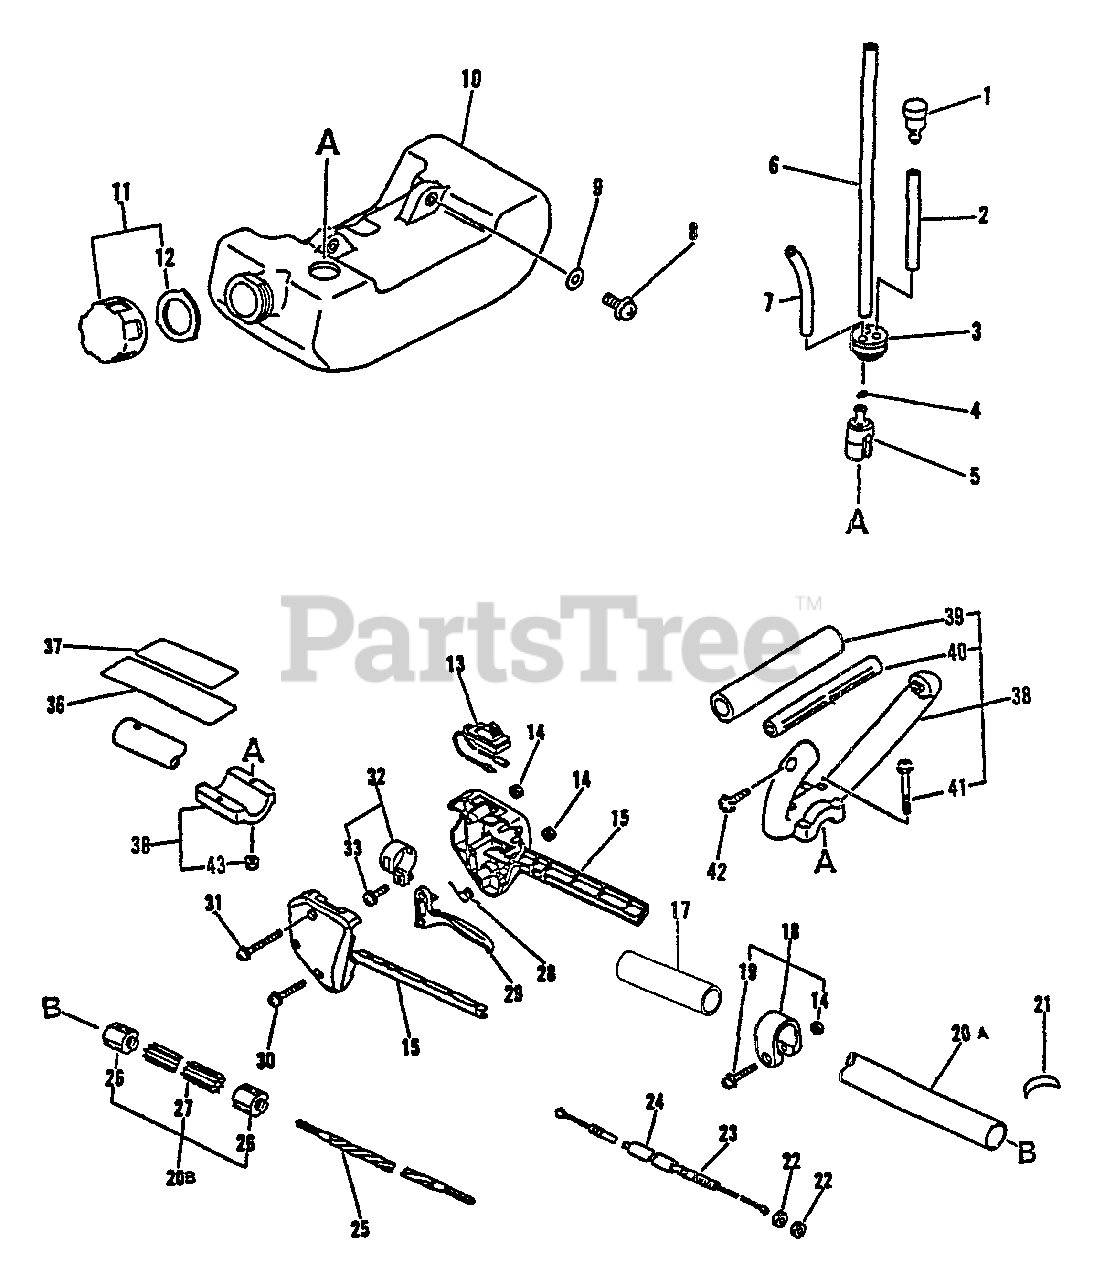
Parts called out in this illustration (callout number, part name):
1	VENT ASSY
2	PIPE, FUEL 3x-5x-70 BLACK
3	GROMMET, FUEL
4	CLIP 6 MM
5	FILTER, FUEL
6	PIPE, FUEL 3x-5x-180
7	PIPE, FUEL RETURN 3×6×90 MM CLEAR
8	SCREW 5×16
9	WASHER 5.5×12×0.8
10	TANK, FUEL
11	CAP ASSY
12	GASKET, FUEL CAP
13	IGNITION SWITCH ASSY
14	NUT M5
15	HANDLE KIT, CONTROL
17	GRIP, HANDLE
18	CLAMP KIT
19	SCREW 5×28
20	MAIN PIPE ASSY 25×1500
21	LABEL - ALIGNMENT
23	CABLE, THROTTLE
25	DRIVESHAFT - FLEXIBLE L= 1522
27	LINER, FLEXIBLE 21.6×1420
28	SPRING, TORSION
29	TRIGGER, THROTTLE
30	SCREW 5×25
31	SCREW 5×35
32	CLAMP KIT
33	SCREW 5×14
34	SCREW 5×40
35	WASHER, FLAT 5.5×10×0.8
36	LABEL - CAUTION
37	LABEL, CAUTION
38	LOOP HANDLE ASSY
39	GRIP, HANDLE
41	SCREW 6×25
42	SCREW 5×30
43	NUT, HEX M6
